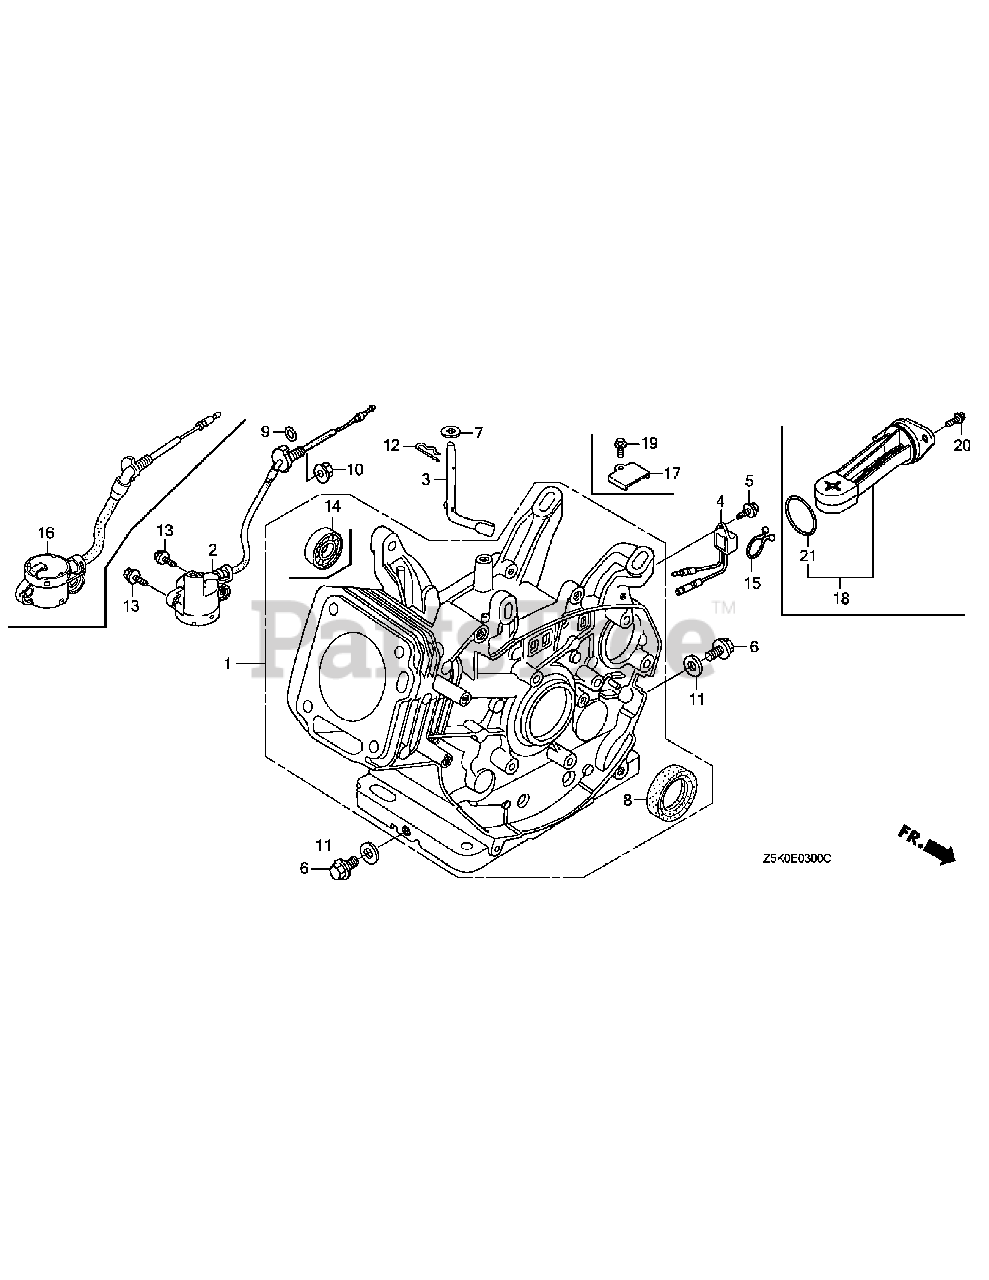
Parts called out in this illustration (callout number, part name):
1	Barrel Assy., Cylinder
2	Switch Assy., Oil Level
3	Shaft, Governor Arm
4	Alert Unit, Oil
5	Bolt, Flange, 6X12(Ct200)
6	Bolt, Drain Plug, 12X15
7	Washer, 8.2X17X0.8
8	Oil Seal, 30X46X8
9	O-Ring, 14Mm(Nok)
10	Nut, Flange, 10Mm
11	Washer, Drain Plug, 12Mm
12	Pin, Lock, 10Mm
13	Bolt, Flange, 6X12
14	Bearing, Radial Ball, 6202
15	Clip, Purse Lock
16	Switch Assy., Oil Level
17	Bracket A, Harness
18	Switch Assy., Oil Level
19	Bolt, Flange, 6X12(Ct200)
20	Bolt, Flange, 6X16(Ct200)
21	O-Ring, 37.9X2.4
